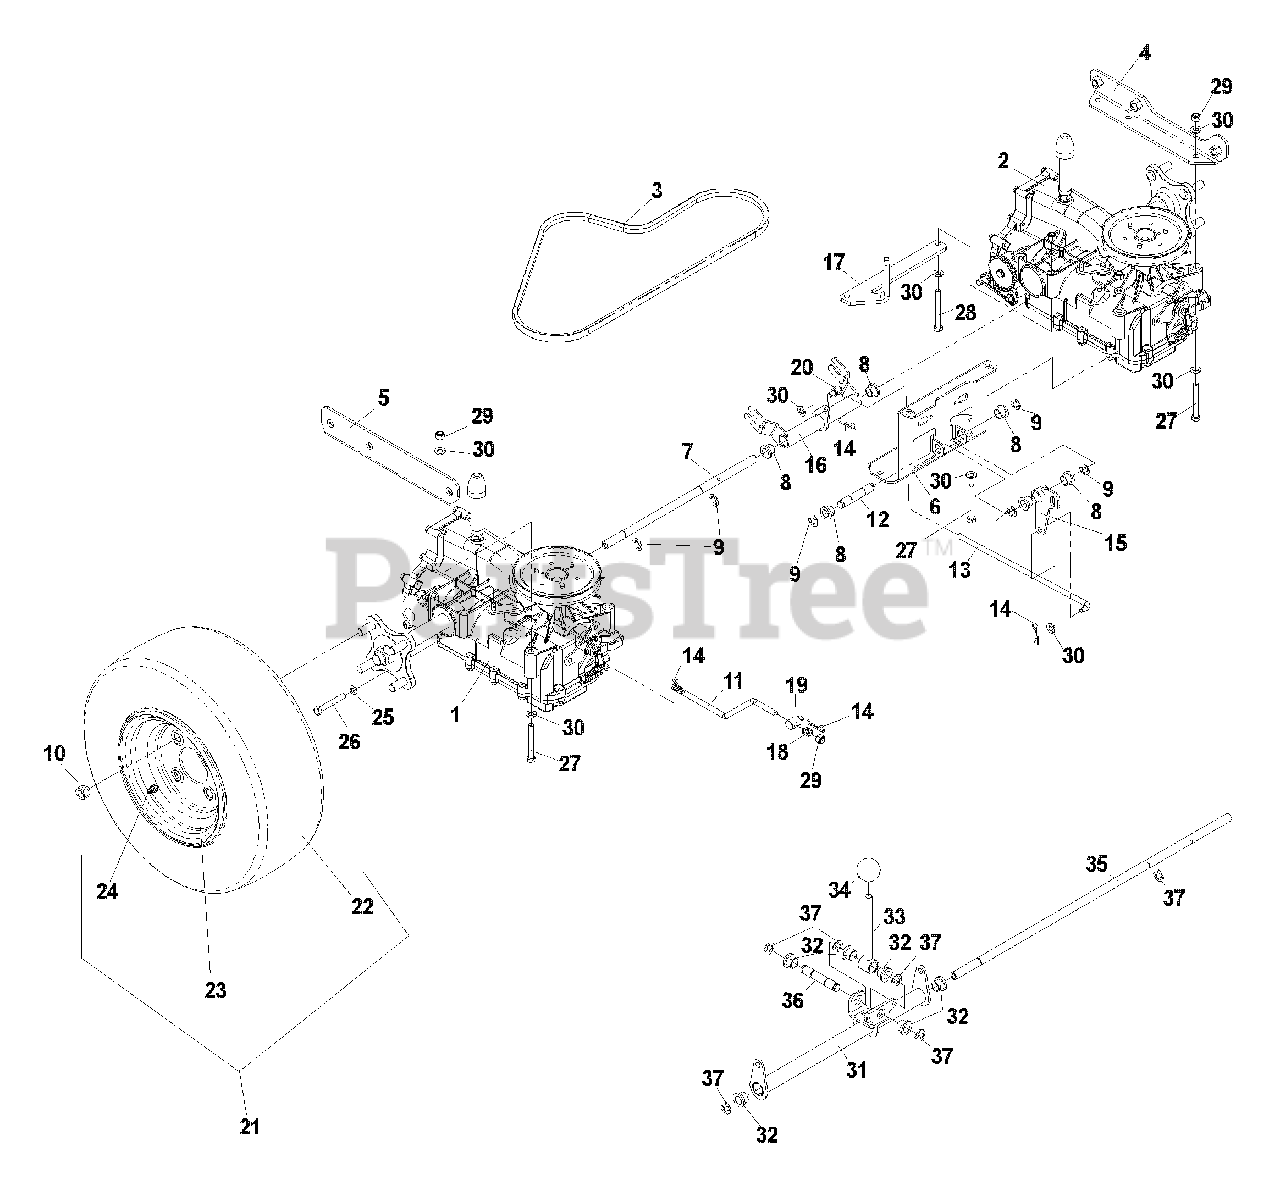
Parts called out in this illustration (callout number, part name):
1	IZT, LEFT (AFTER SERIAL NO. 042627905)
1	IZT, LEFT (BEFORE SERIAL NO. 042627905)
2	IZT, RIGHT (AFTER SERIAL NO. 042627905)
2	IZT, RIGHT (BEFORE SERIAL NO. 042627905)
4	IZT SUPPORT, RIGHT
5	IZT SUPPORT, LEFT
6	IZT SUPPORT, REAR
7	IZT CONNECTOR
8	BUSHING, NYLON FLANGED
9	E-RING, 1/2"
10	LUG NUT, 1/2"
11	IZT BYPASS LINKAGE
13	BRAKE LINKAGE
14	HAIRPIN COTTER
15	BRAKE BELLCRANK, REAR
16	BRAKE BELLCRANK, FRONT
17	CLUTCH TIE DOWN
18	SPRING, TANK MOUNT
20	ADJ. SWIVEL, SHORT
21	TIRE AND WHEEL ASSEMBLY
24	VALVE STEM
25	LOCKWASHER, 5/16
26	HCS, 5/16-18 X 2 1/4, GR8
27	HCS, 5/16-18 X 2 1/2
28	HCS, 5/16-18 X 2 3/4
29	NUT, 5/16C, NYLOC
30	WASHER, 5/16, SAE
31	ACTUATOR ARM
32	BUSHING, NYLON, FLANGED
37	E-RING, 1/2"
